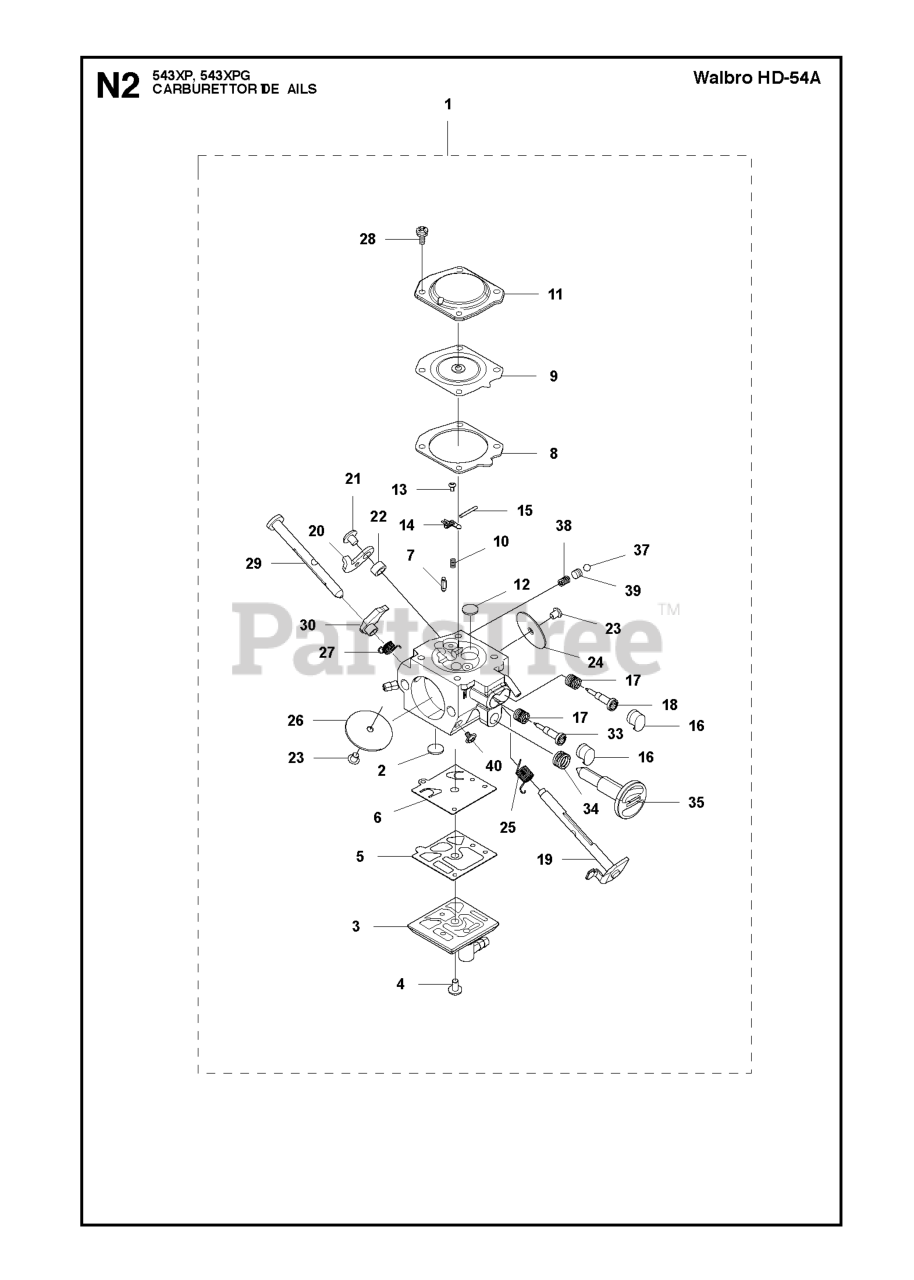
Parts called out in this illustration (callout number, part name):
1	CARBURETTOR ASSY HD
2	SCREEN
3	COVER ASSEMBLY PUMP 21-3780
4	SCREW Z149181130
5	GASKET
6	95-75 DIAPHRAGM Z335081260
7	VALVE INLET
8	GASKET
9	DIAPHRAGM ASSEMBLY METERING 95
10	SPRING
11	COVER METERING DIAPHRAGM 21-48
12	PLUG
13	SCREW
14	LEVER
15	PIN
16	CAP LIMITER
17	SPRING
18	NEEDLE
19	SHAFT ASSY
20	LEVER THROTTLE 18-3551
21	SCREW
22	SPACER
23	SCREW 96-3240
24	VALVE THROTTLE 34-314
25	SPRING 98-3706
26	VALVE CHOKE 34-3504
27	SPRING 98-3718
28	SCREW ASSY
29	SHAFT ASSY CHOKE 22-4356
30	LEVER FAST IDEL 18-3566
33	NEEDLE HIGH SPEED
34	SPRING
35	SCREW
37	BALL
38	SPRING
39	PISTON ASSY
40	SCREW
